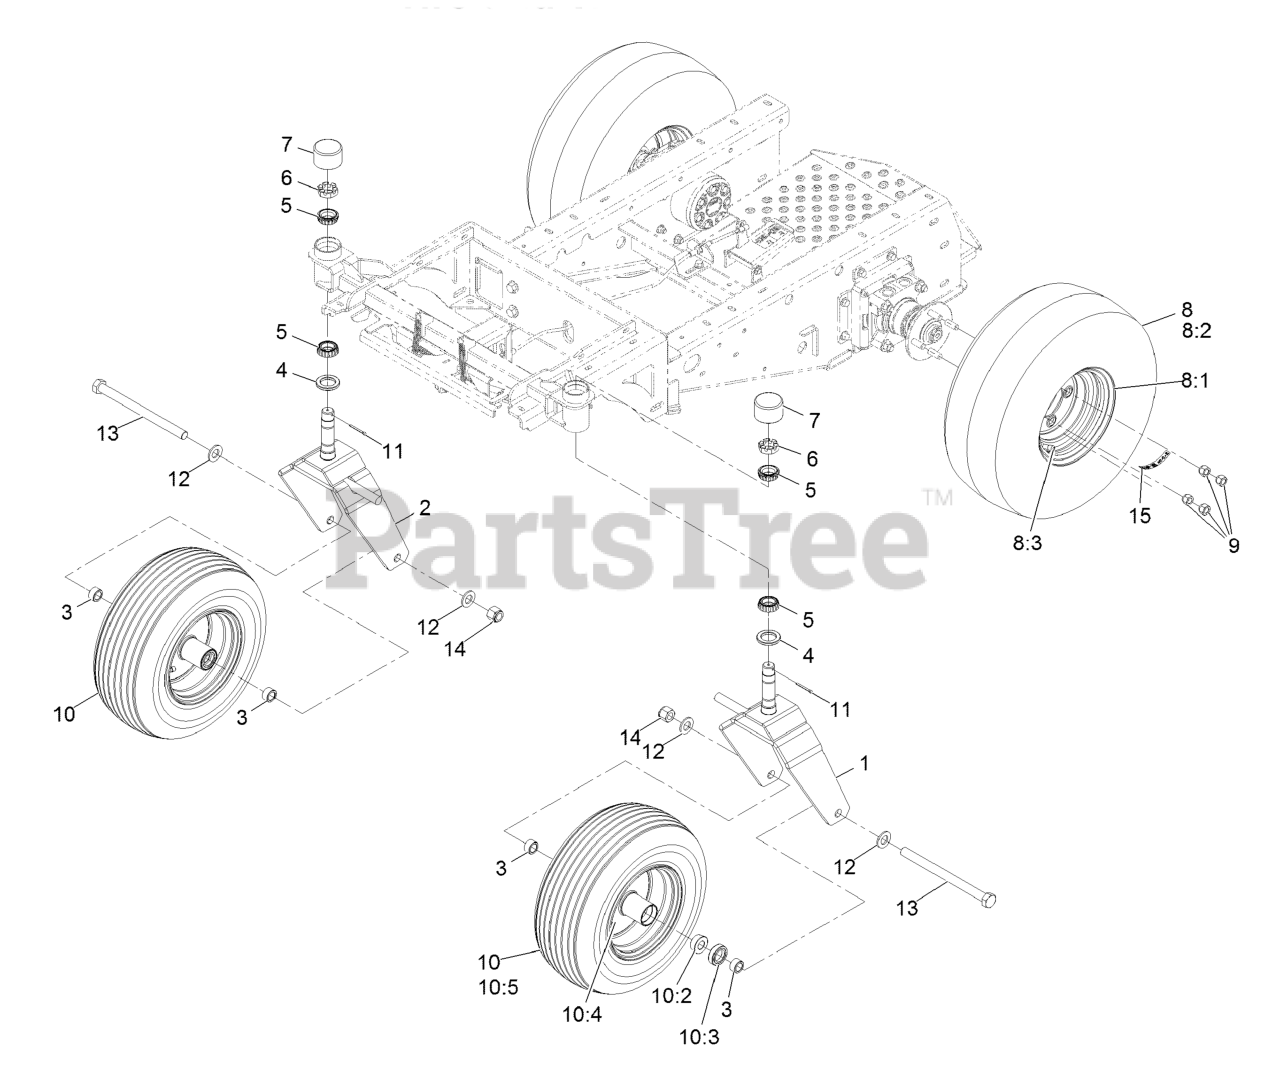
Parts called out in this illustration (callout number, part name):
1	X-REF TO 135-5441-03
2	X-REF TO 135-5446-03
3	SPACER-AXLE
4	SEAL-GREASE
5	CONE-BEARING, OUTER
6	NUT-SHH
7	CAP-DUST, RUBBER
8	WHEEL AND TIRE ASM
8:1	RIM-8X5.375, CENTERED
8:2	Tire- 20 X 8 4 Ply
8:3	Stem-Valve
9	NUT-LUG
10	WHEEL AND TIRE
10:2	BEARING-CONE, TAPERED ROLLER
10:3	SEAL-CASTER
10:4	VALVE
10:5	Tire-Rib
11	Pin-Cotter
12	WASHER-FLAT
13	SCREW-HH
14	NUT-LOCK, NI
15	DECAL-TORQUE, WHEEL HUB LUG
